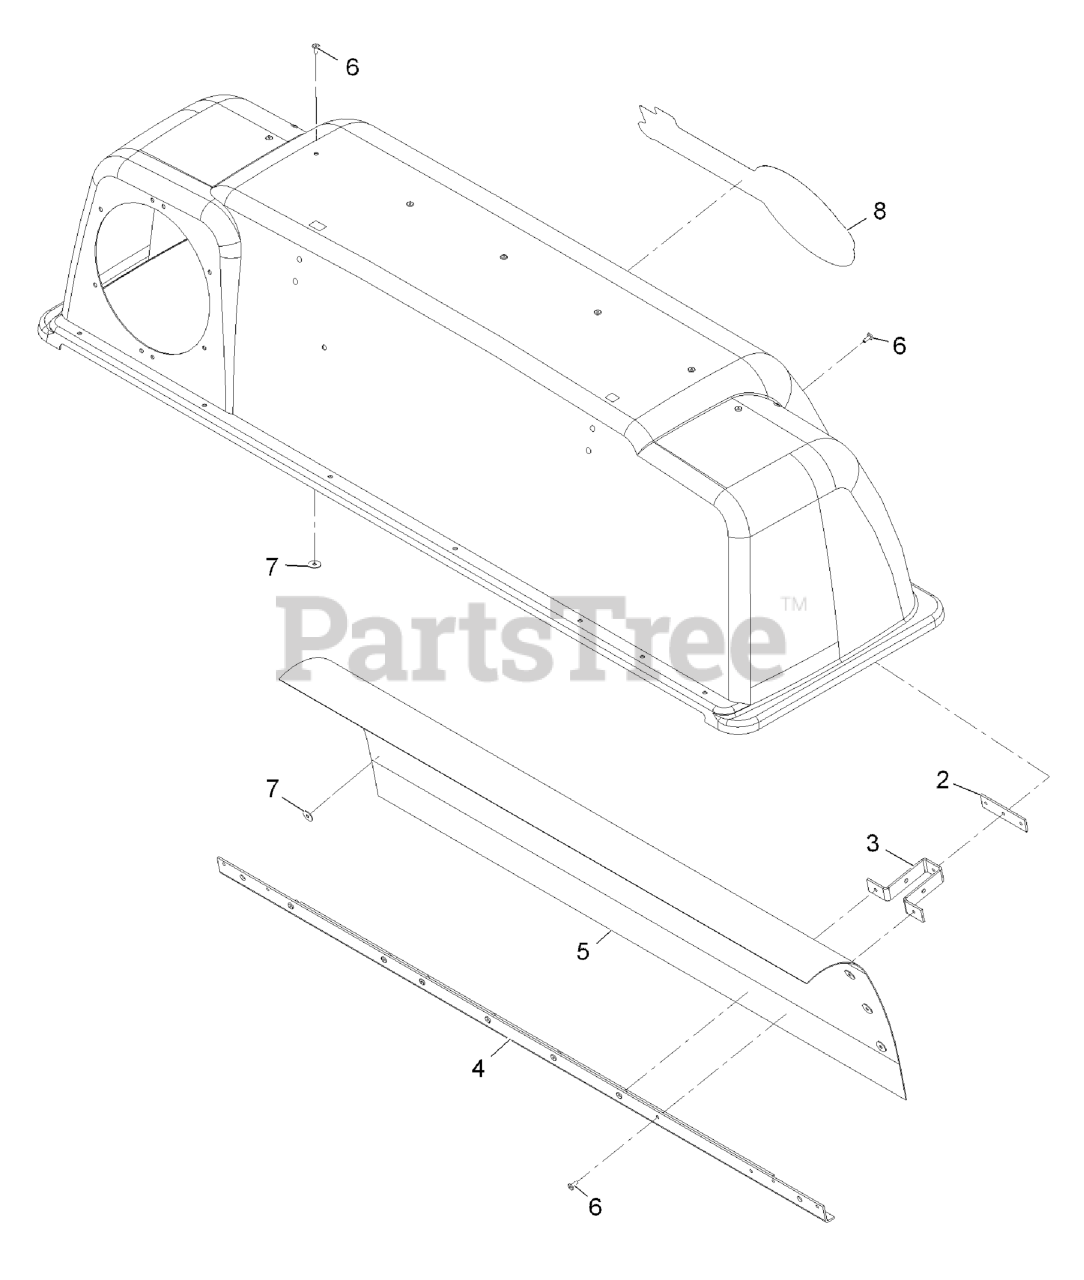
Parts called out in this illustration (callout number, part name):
2	PLATE-LATCH, REINFORCEMEN
3	BRACKET-MOUNT
4	SUPPORT-SCREEN
5	SCREEN-BAGGER
6	RIVET-BLIND
7	WASHER-FLAT
8	DECAL-EXMARK LOGO
